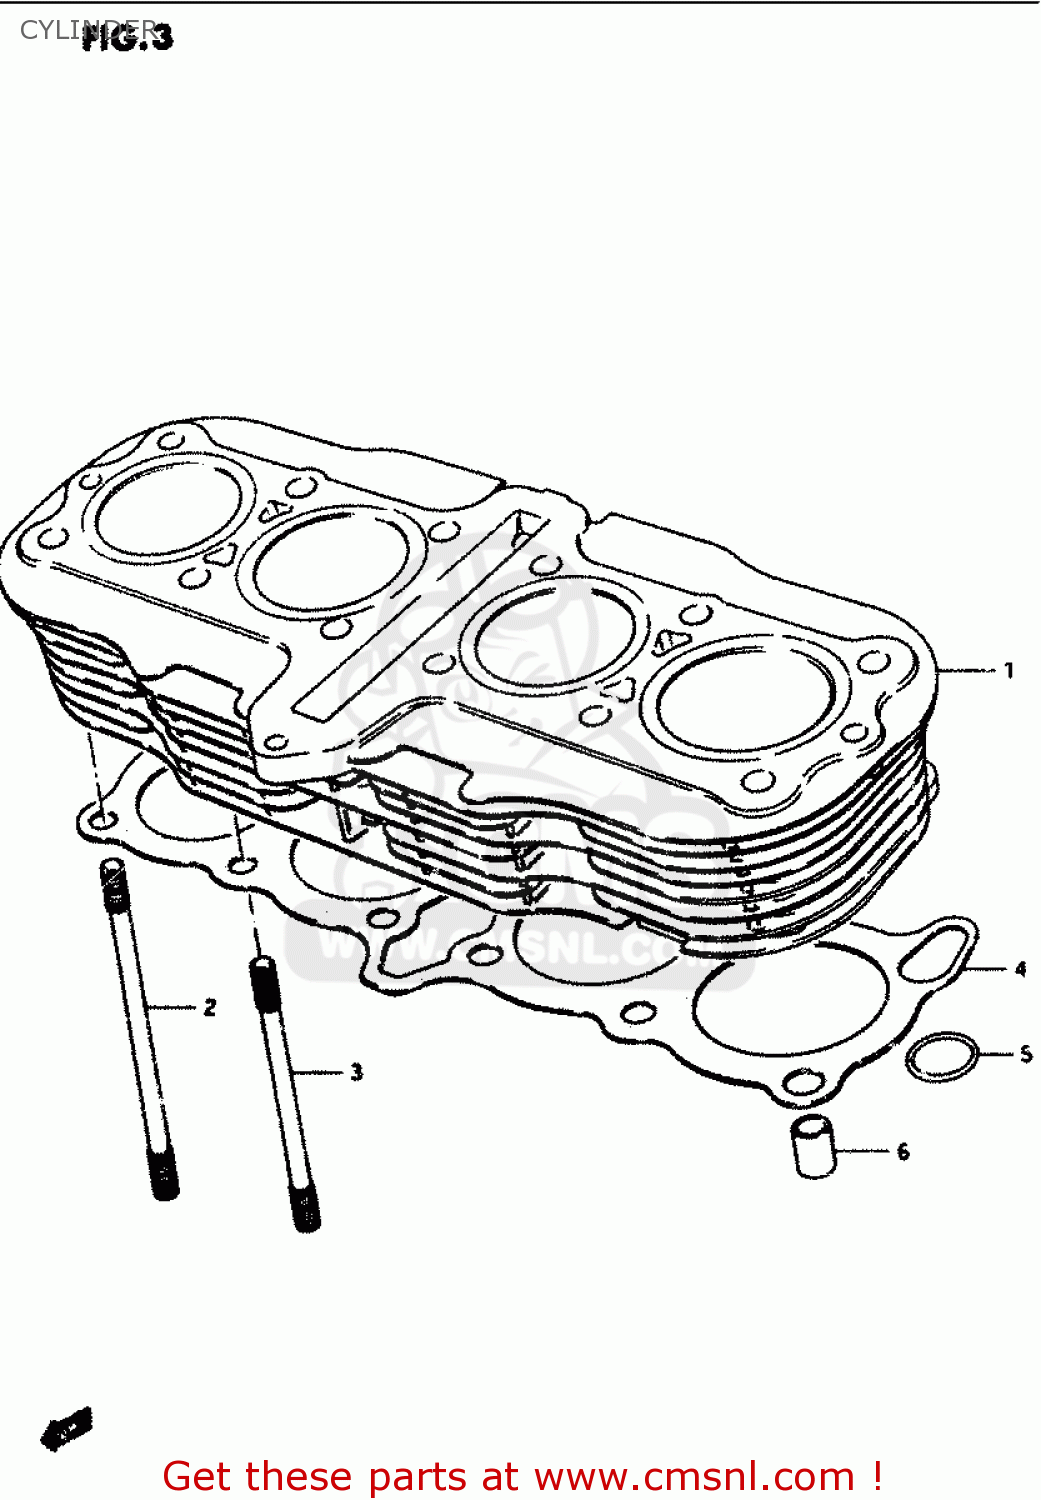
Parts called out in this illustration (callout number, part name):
1	CYLINDER
2	BOLT,STUD
3	STUD
4	GASKET,CYLINDER (MCA)
5	O-RING
6	PIN
